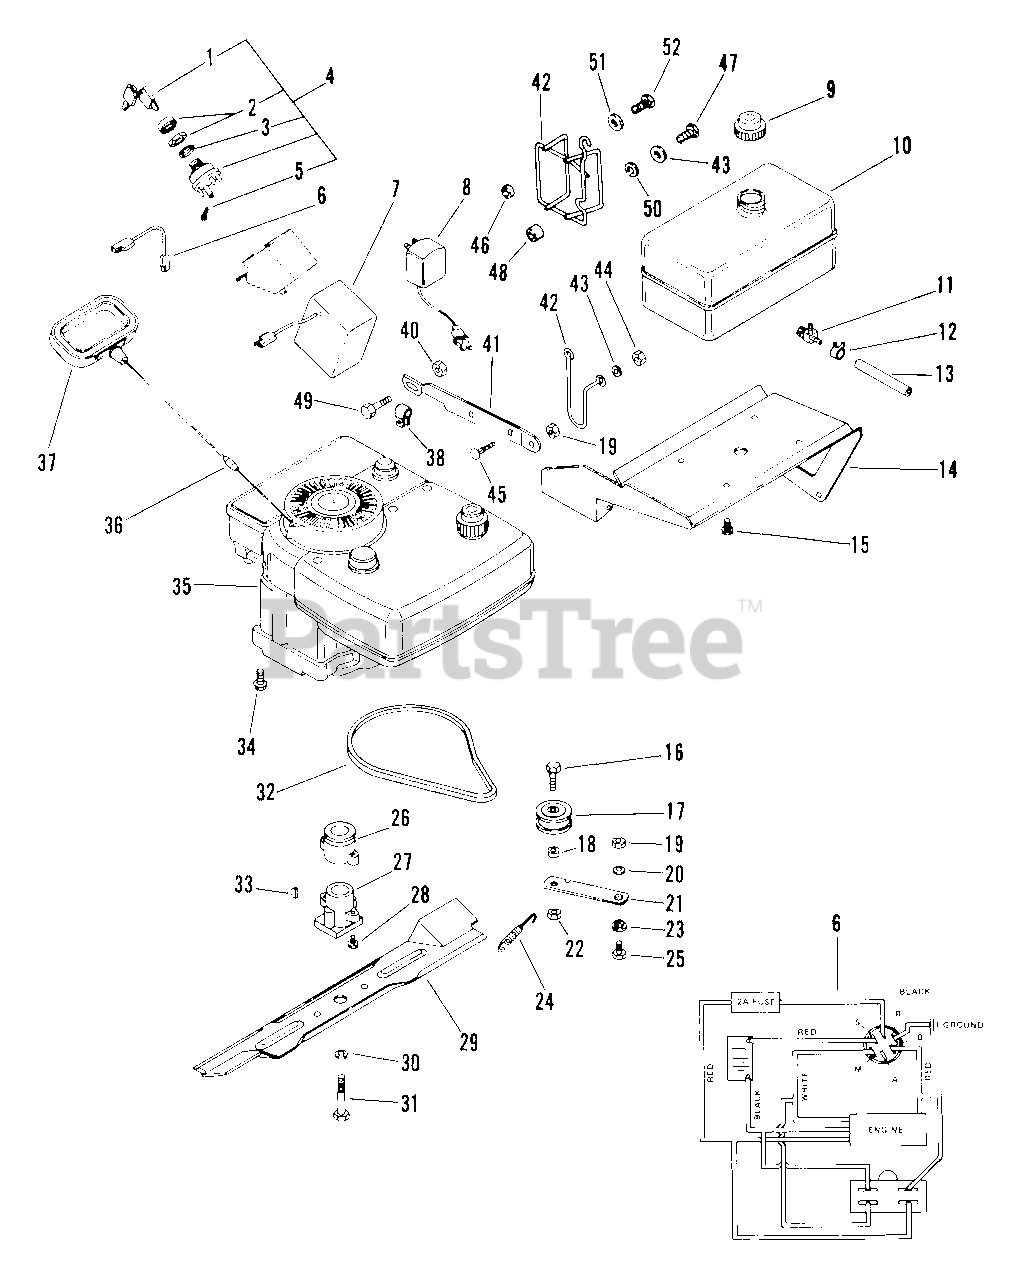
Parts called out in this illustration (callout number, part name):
1	KEY SET
2	NUT-PANEL .625-32 GRECO
2	CAP - IGNITION SWITCH
2	NUT .812-20 PL
3	WSHR-LK-INT .625X.045 PL
3	WSHR-LK-INT .813X.020 PL
4	KEY SWITCH
5	SCR-MCH 10-32X.32 SLRH PL
6	WIRE HARNESS
7	BATTERY
8	BATTERY CHARGER
8	BATTERY CHARGER UK FRIW0 56421
8	BATTERY CHARGER EUR FRIW56413
9	FUEL CAP
10	FUEL TANK, 1 GAL
11	FUEL SHUT OFF VALVE
12	CLAMP-FUEL LINE
13	FUEL LINE 1/4 X 1.56"
13	FUEL LINE, 17 INCHES
14	FUEL TANK MOUNT
15	SCR-TAP .250-14X.75 HWH PL
16	BLT-HEX .44-14X1.25 PL GR2
17	IDLER-FLAT 1.75 X .47
18	SPACER .52 X .45 X .34
19	NUT-LK .312-18 GR A PL
20	WSHR-FL-STL .323X.625X.062 PL
21	IDLER ARM
22	NUT-LK .437-14 GR A PL
23	BSHG-FLG .325X.501X.250X1.120
24	SG-TENS .043X.44X3.31 WLD 5.8
25	BLT-HEX .31-18X.75 PL GR2
26	TRACTION DRIVE SHEAVE
26	DRIVE PULLEY, COMMERCIAL
27	BLADE ADAPTER
28	SCR-TAP 10-24X1.0 HWH PL TR
29	21" MOWER BLADE
30	WSHR-LK .375X.094 MED PL
31	BLT-HEX .38-24X2.00 PL GR5
32	V-BELT, 3L-COGGED
33	KEY-WDRF .156X.625X.25 SAE 6
34	SCR-TAP .375-16X1.0 HWH PL TR
35	ENGINE, BRIGGS 5 HP COMMERCIAL
35	ENGINE TEC. BBC RECOIL 5 HP.
35	ENGINE,4HP. 2 CYCLE TEC.
35	ENGINE, 4HP. 2 CYCLE B/S
35	ENGINE TEC. 5 HP ELEC. START
35	ENGINE TEC. 5 HP RECOIL
35	ENGINE TEC. 5 HP OHV RECOIL
35	ENGINE B&S 5 HP RECOIL
36	ROPE BULLET
37	HANDLE, RECOIL START
40	NUT-FLG. .312-18 PL
41	ANTI-VIBRATION STRAP
41	ENGINE BRACE
42	MUFFLER SHIELD
43	WSHR-FL-STL.281X.62X.065 PL
44	NUT-HEX .250-20 PL
45	BLT-RDHDSQNK .25-20X1.50 SHTPL
46	SPACER .272X.438X.145
47	BLT-HEX .25-20X1.25 PL GR5
48	BSHG-SLV .260X.625X.50
49	BLT-HEX .25-20X.63 PL GR2
50	WSHR-LK .250X.077 HVY PL
51	WSHR-FL-STL .194X.492X.047 PL
52	SCR-TAP 10-24X.75 HWH PL TR
